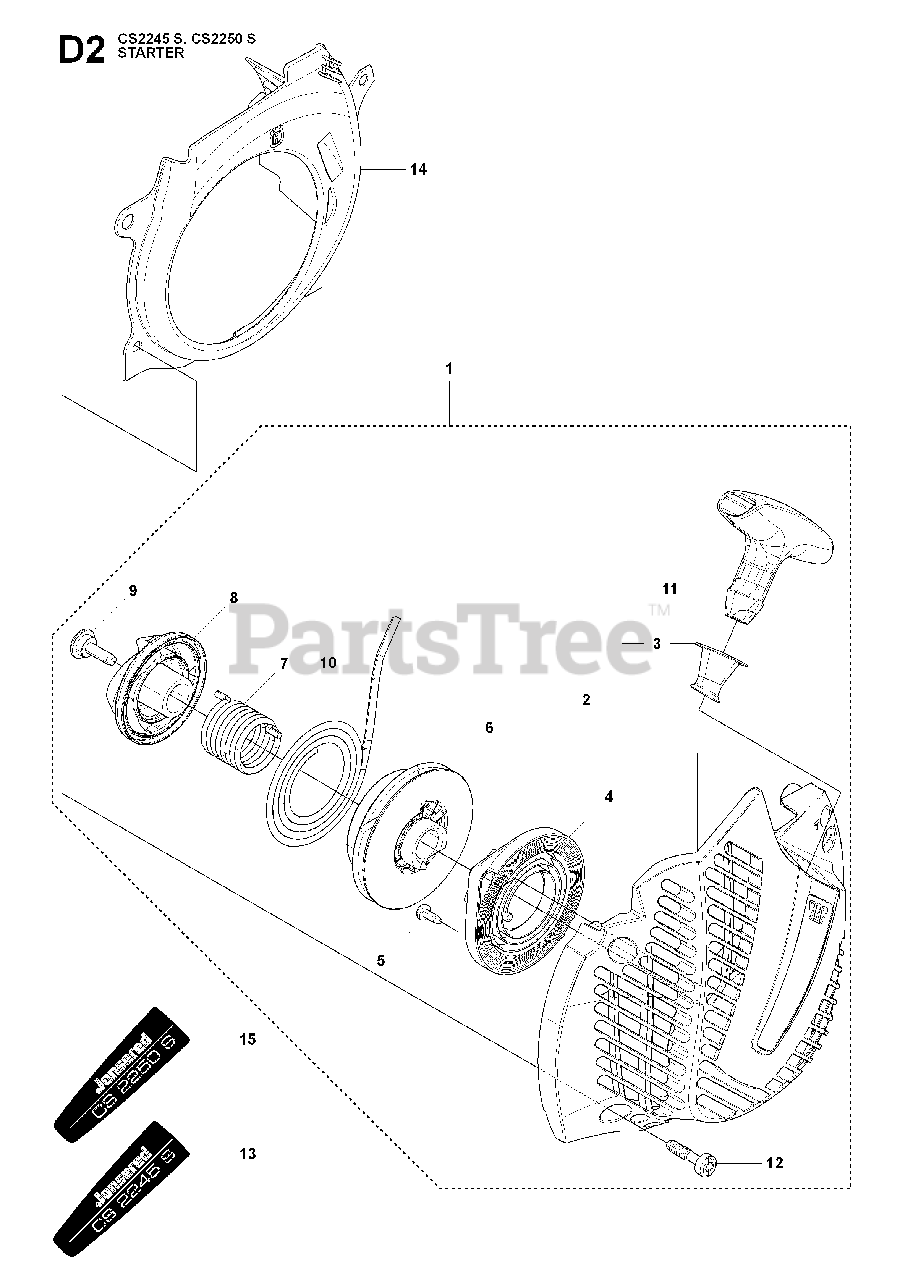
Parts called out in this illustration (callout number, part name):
1	STARTER ASSY
4	RETURN SPRING
6	STARTER PULLEY
10	STARTER ROPE
11	STARTER HANDLE
14	COOLING AIR CONDUCTOR
